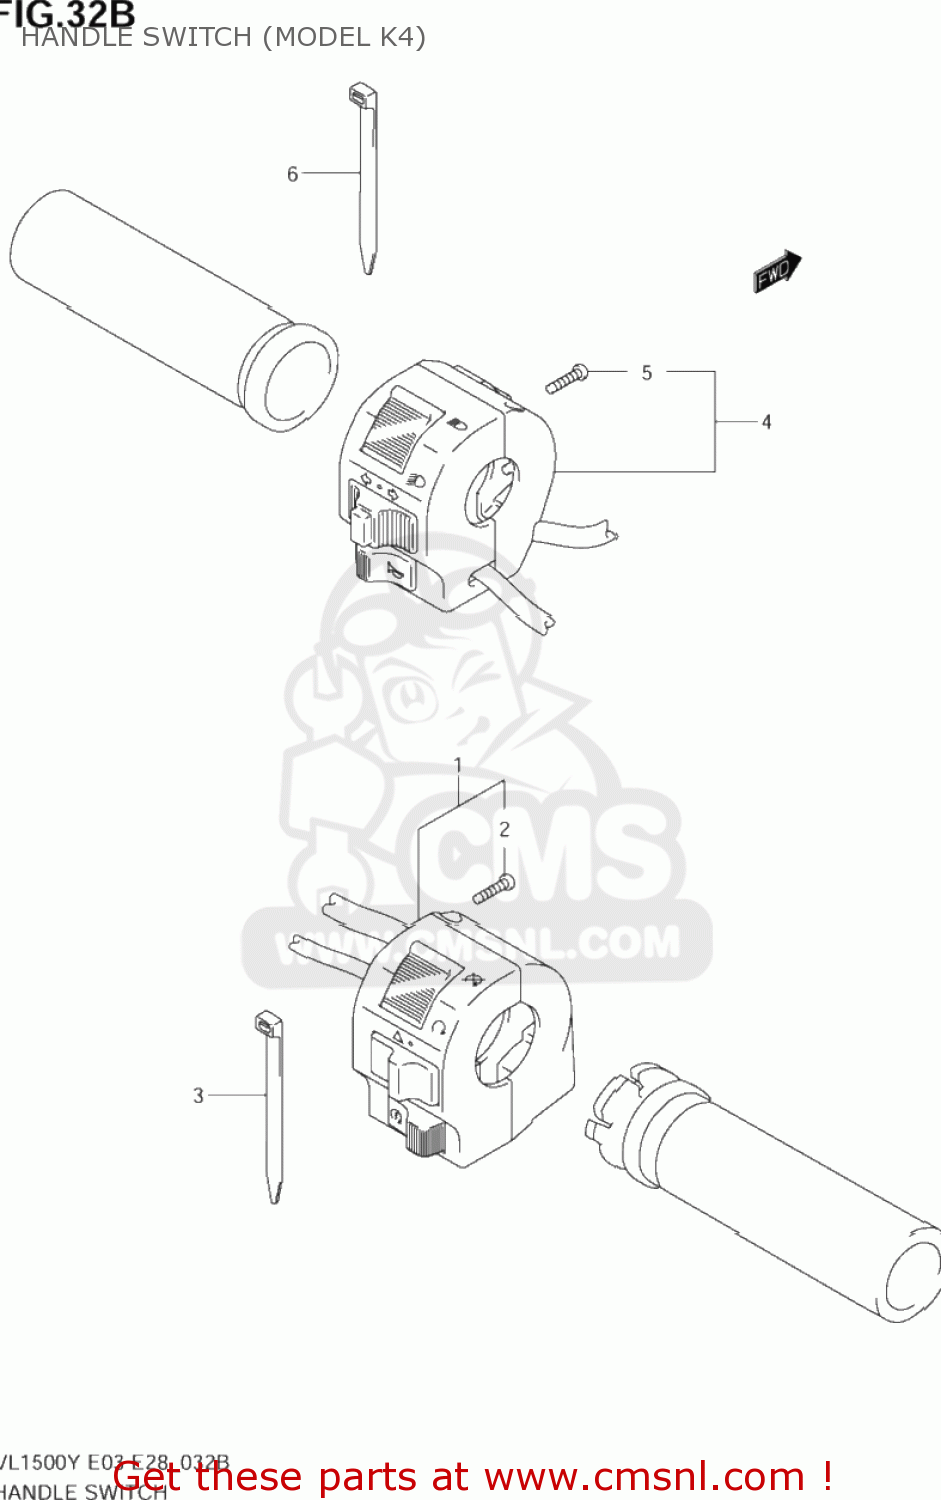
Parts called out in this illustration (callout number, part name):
1	SWITCH ASSY,HANDLE,R
2	SCREW
3	CLAMP(L:145)
4	SWITCH ASSY,HANDLE,L
5	SCREW
6	CLAMP(L:145)
